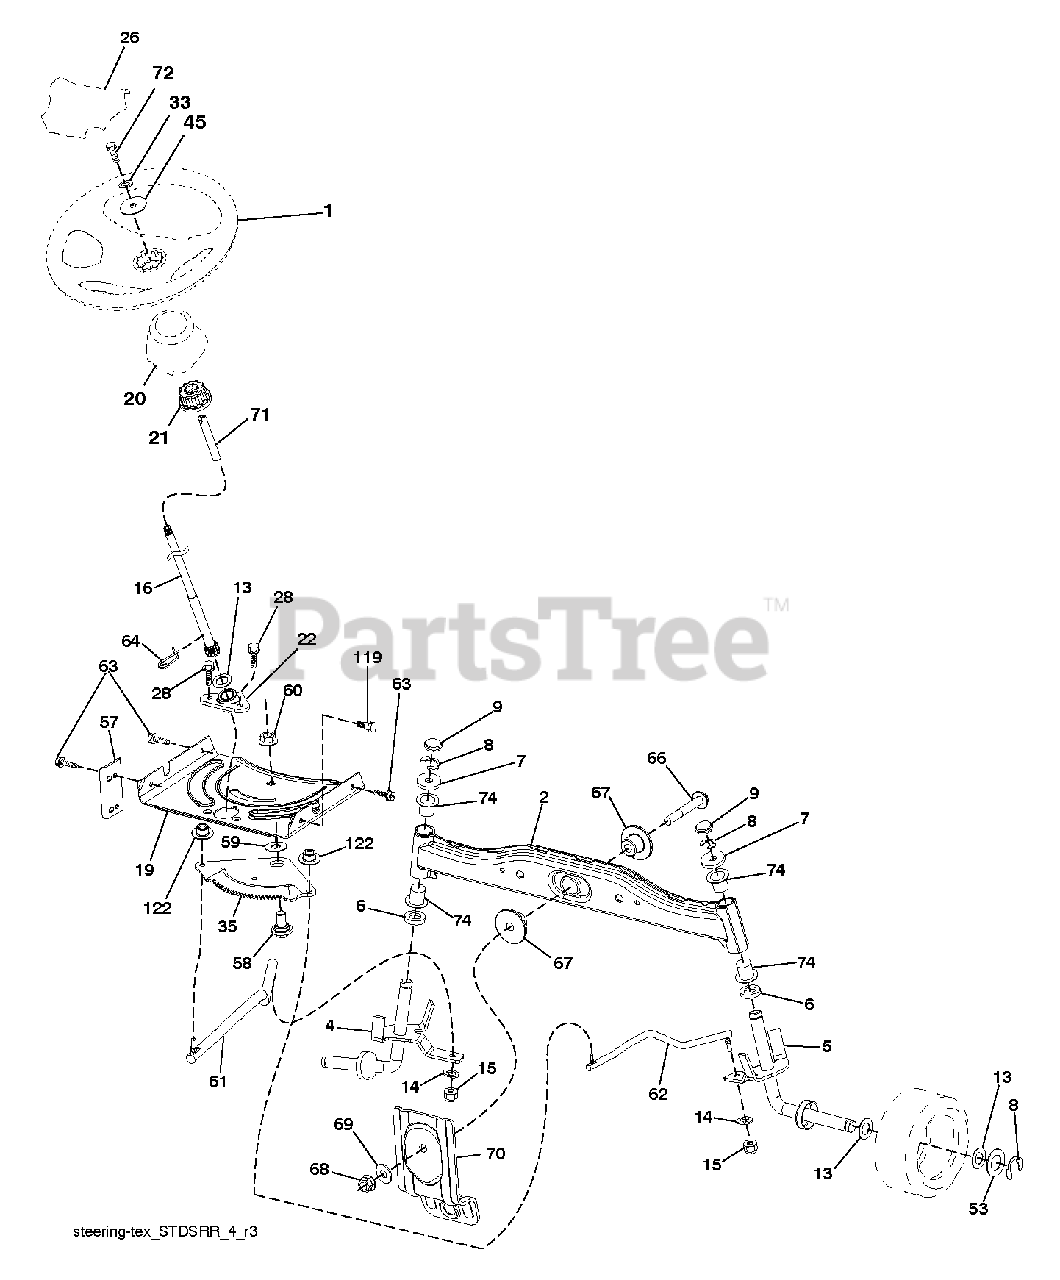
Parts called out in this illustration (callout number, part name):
1	WHEEL.STEERING.STDSRR.BLK/OV
2	AXLE HALF ASM-WELDED
8	RING CLIP
9	CAP.SPINDLE
14	WASHER, LOCK 3/8
15	NUT CROWNLOCK 3/8-24
16	SHAFT.STEER.3/4.PLATED.TEX
19	PLATE.STEER.DDL.NLT/NG
20	BOOT.STEERING.PREDATOR.LT.BLAC
21	ADAPTER, WHEEL STNG..
22	STEERING.SUPT.LOWER.
26	CAP.WHL.STRNG.STDSRRD.SRS.BLK
28	SCREW, 3/8-16X3/4
33	LOCKWASHER
35	GEAR.SECTOR.PLATE.DDL.
45	WASHER.11/32
53	WASHER.HARDENED
57	BRACKET.UPSTOP.TEX
58	BOLT.SHOULDER.SECTOR.P
59	WASHER.THURST.SECTOR.S
60	NUT FLANGE LOCK 5/8-11
61	DRAGLINK.LH.BALLSTUD.D
62	DRAGLINK.RH.BALLSTUD.D
63	SCREW
64	RETAINER.CLIP.SPRING.S
66	BOLT HEX FGHD 7/16-14 X 3 SERR
67	BUSHING.PM.FRONT AXLE
68	NUT.LOCK.FLANGE.7/16
69	WASHER.1.5X.505X.118
71	SHAFT.EXTEN.STRG.SPLINE
72	BOLT 5/16-18 X 4 W/PATCH
74	BRNG T
119	SHOULDER BOLT 5/16-18TT
